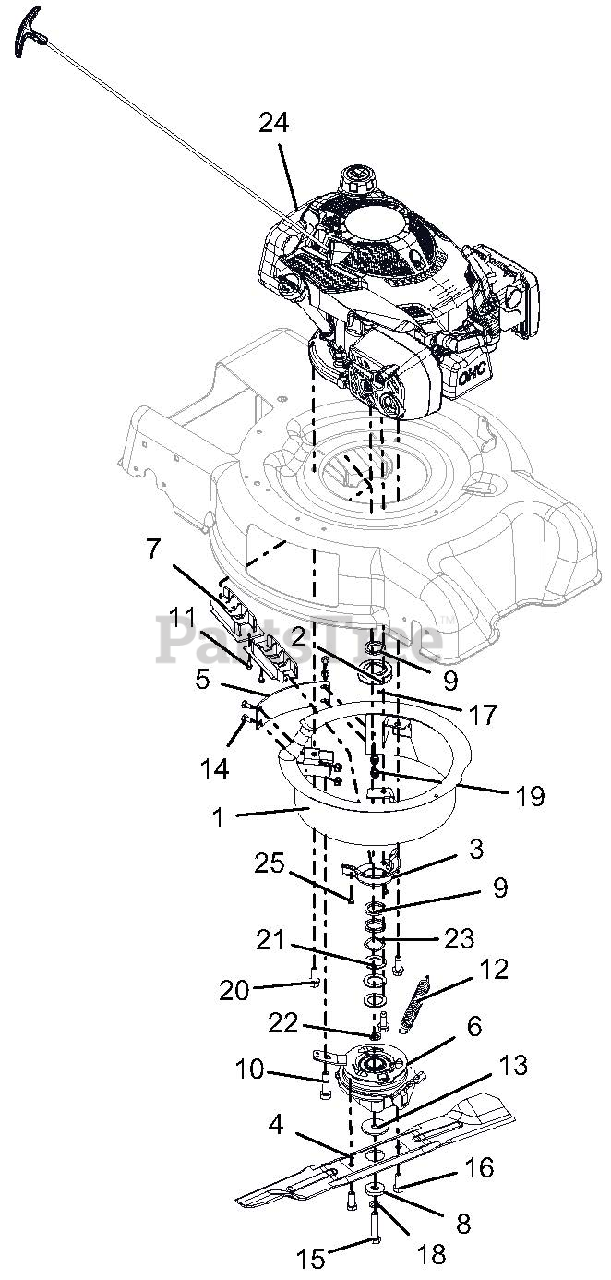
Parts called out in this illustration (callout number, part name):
1	WLDMT, ENCLOSURE - BBC
2	PULLEY,MACHINED POWDER METAL
3	GUIDE, BELT CRANK
4	BLADE, MOWER 21" HIGH LIFT-BBC
5	BAFFLE, BBC
6	CLUTCH, RAZOR/XD3, 25MM
7	GUIDE, BELT INNER
8	WSHR-FL-STL .44X1.25X.25 YWZC
9	SPCR, 1.00 X 1.375 X .179
10	BLT,SHLDR 12MM X 25 W/ M10 THD
11	SCR-TAP 10-24X.375 PRE-COAT 80
12	SPRING, EXTENSION BBC
13	WSHR-FL-STL .469X1.75X.10 YWZC
14	@BLT-HEX .25-20X.50 GR5 YWZC
15	BLT-HEX .44-20X2.00 GR5 YWZC
16	BLT-HEX M10 X 1.5X25 YWZC
17	KEY-SQ .188X.188X.250
18	WSHR-FL-STL .45X.75X.033
19	@NUT-LK-TOP-FLG .25-20 YWZC
20	@SCR-TAP .38-16X1.00 HWH TR YZ
21	WSHR-FL-STL 1.010X1.505X.062YZ
22	WSHR-FL-STL .459X.750X.105 YZC
23	WASHER - WAVE 1.09X1.37X.016
24	ENGINE, SUBARU 175CC VERT. BBC
25	SCR-TAP 10-24X.25 CRSLPH TR YZ
